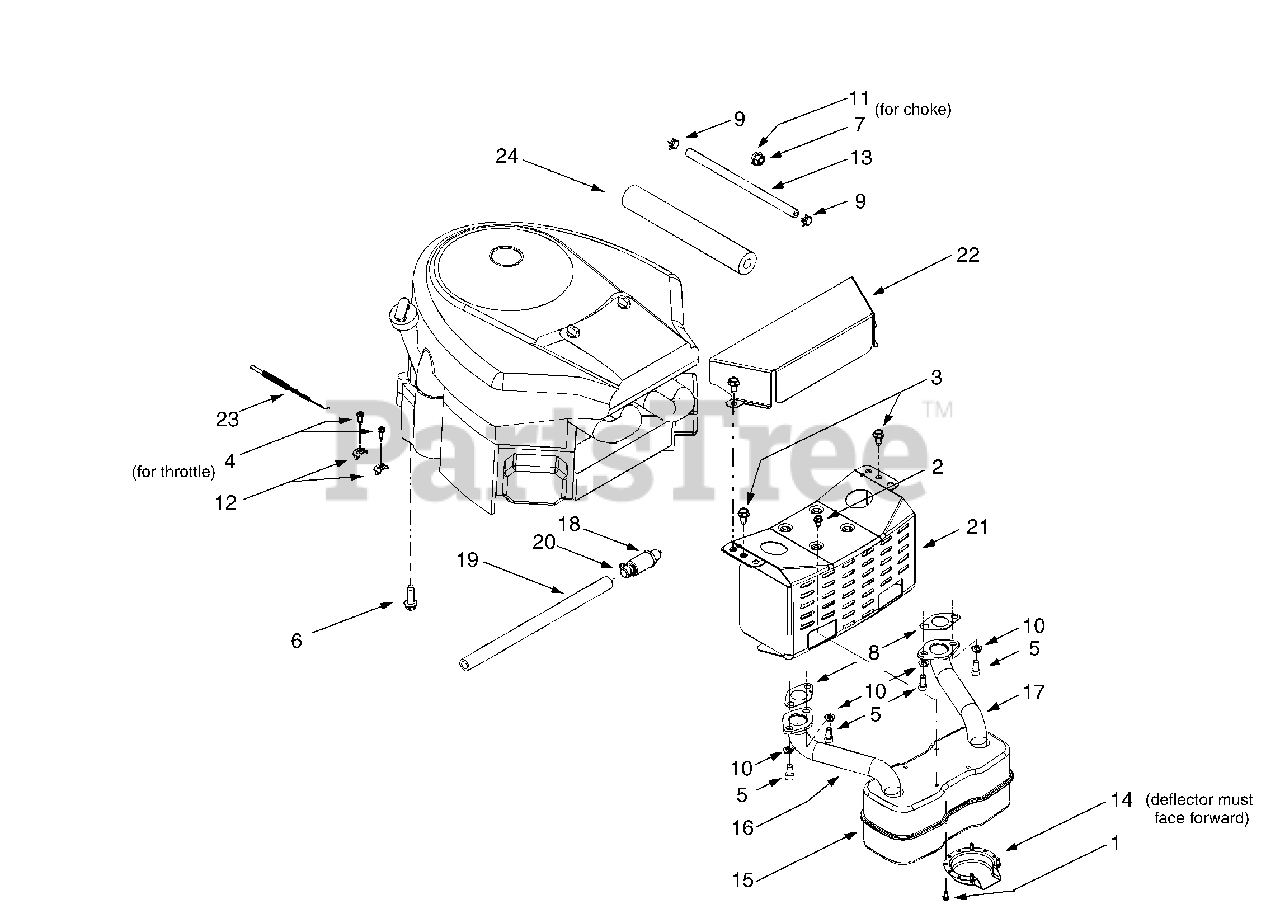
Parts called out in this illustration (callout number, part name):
1	Self Tapping Screw, #8-32 x .375
2	Self Tapping Screw, 1/4-20 x .5
3	Self Tapping Screw, 5/16-18 x .625
4	Screw, #10-32 x .625
5	Socket Cap Screw, 5/16-18 x .625
6	Self Tapping Screw, 3/8-16 x 1.25
7	Hex Nut, 3/8-16
8	Exhaust Gasket (Intek Twin)
9	Hose Clamp
10	Lock Washer, 5/16
11	Flat Washer, .406 x .875 x .059
12	Casing Clamp
13	Fuel Line Hose
14	Muffler Deflector
15	Muffler (Intek Twin)
16	RH Exhaust Pipe (Intek Twin)
17	LH Exhaust Pipe (Intek Twin)
18	Oil Drain Valve
19	Oil Drain Hose
20	Oil Drain Cap
22	Engine Heat Shield (Intek Twin)
23	Throttle Cable (Intek Twin & Kohler Twin)
24	Foam (fits over fuel line)
